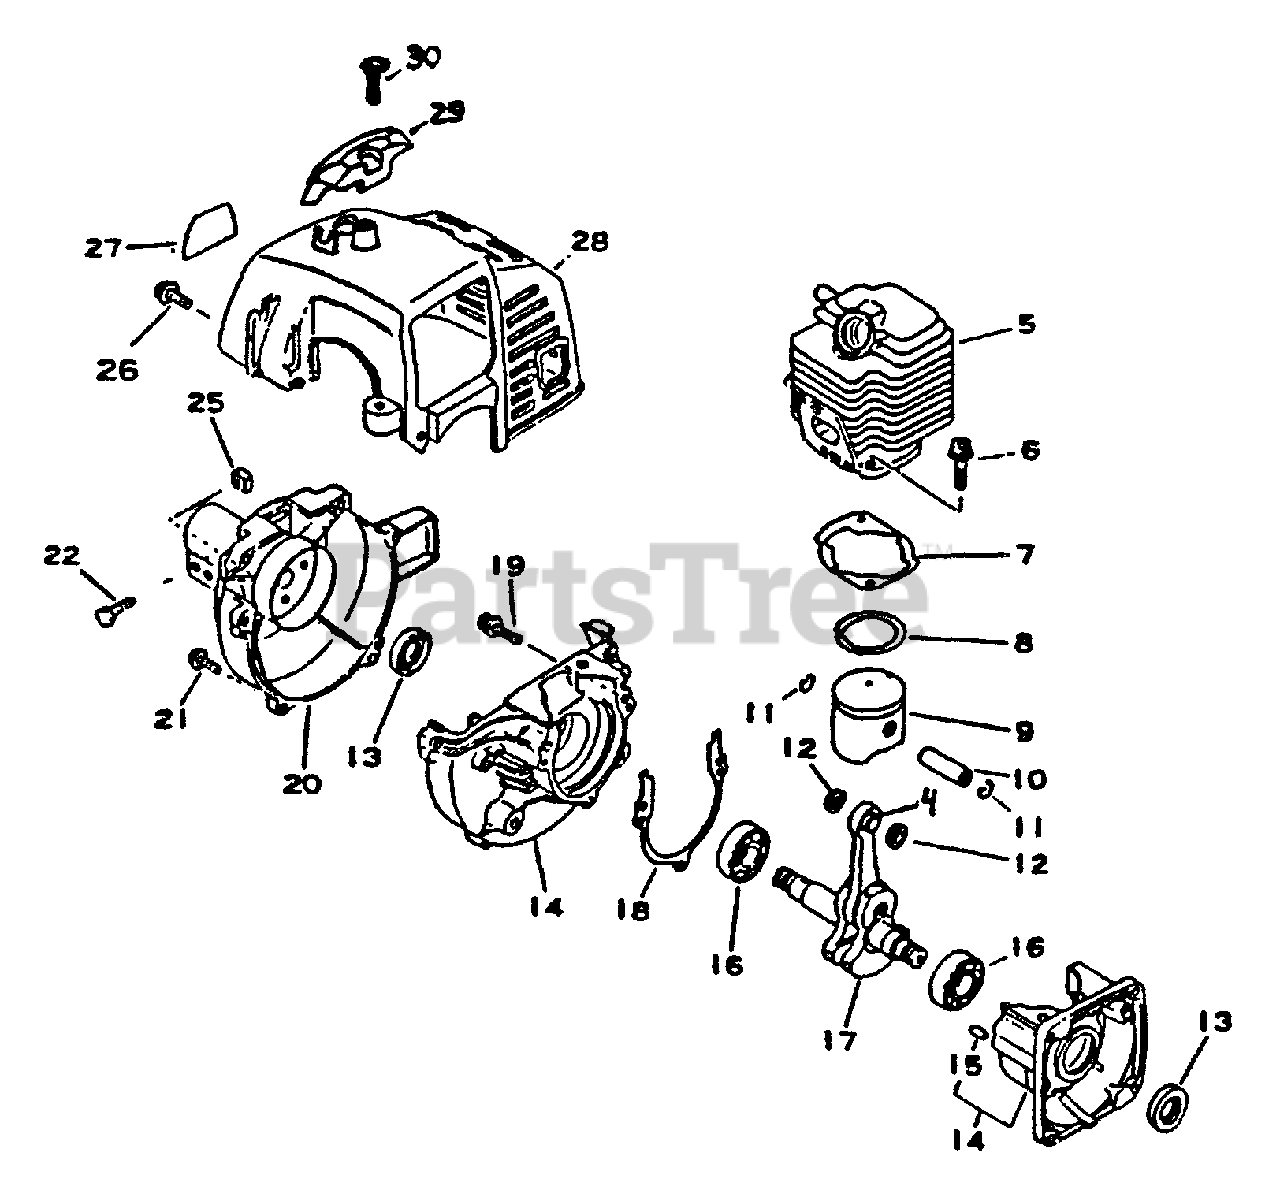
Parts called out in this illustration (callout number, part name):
4	BEARING, NEEDLE
5	CYLINDER
6	SCREW - 5X22
7	GASKET, CYLINDER
8	RING, PISTON
9	PISTON
10	PIN, PISTON
11	RING, RETAINING
12	SPACER, PISTON
13	SEAL, OIL
14	CRANKCASE KIT
15	PIN - LOCATING
16	BEARING, BALL - 6201
17	CRANKSHAFT ASSY
18	GASKET, CRANKCASE
19	SCREW - 5X28
20	FAN CASE ASSY
21	SCREW - 4X18
22	BOLT - 5X28
25	NUT - 5 -- SQUARE
26	SCREW - 4X16
27	LABEL - MODEL
28	COVER, ENGINE
29	GUARD, TOP - BLACK
30	SCREW - 5X16 -- TAPPING
